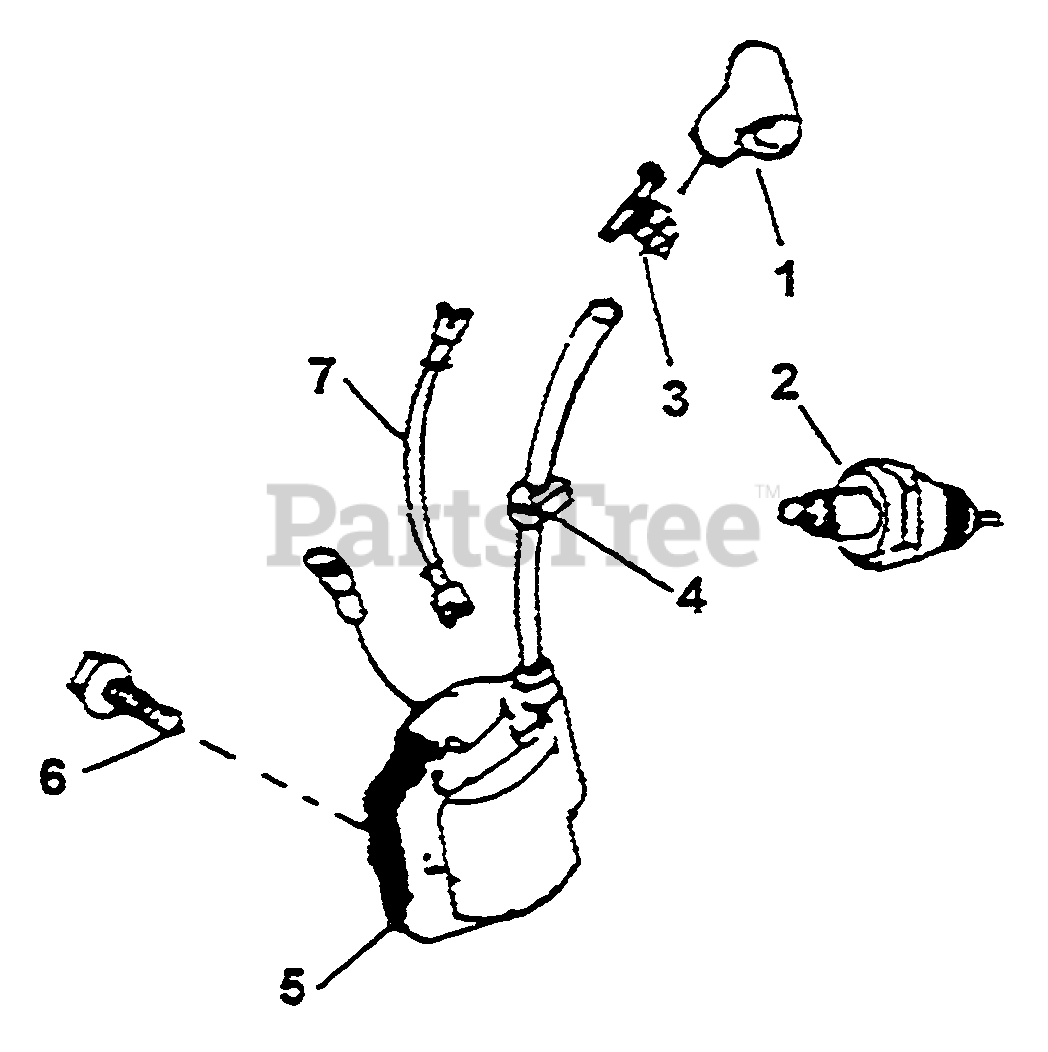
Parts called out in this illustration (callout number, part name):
2	SPARK PLUG
3	CONNECTOR
5	COIL, IGNITION
7	WIRE, GROUND
